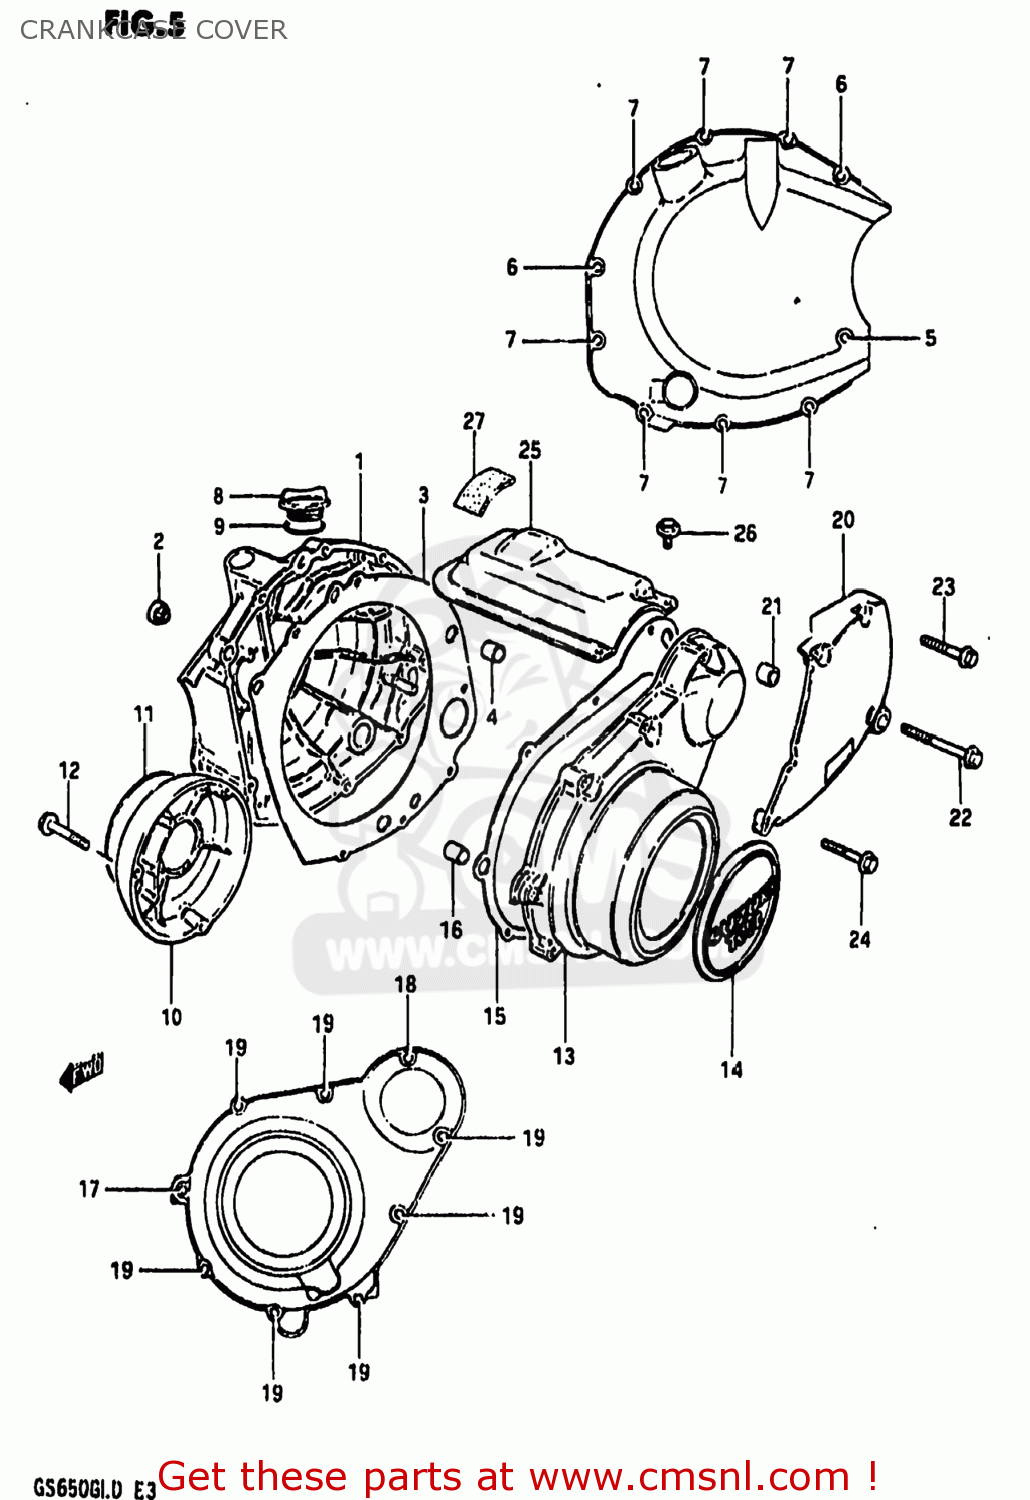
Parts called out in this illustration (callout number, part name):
1	COVER,CLUTCH
2	LENS,OIL LEVEL CHECK
3	GASKET,CLUTCH COVER (MCA)
4	PIN
5	BOLT (6X65)
6	BOLT (6X40)
7	BOLT (6X30)
8	PLUG
9	O-RING
10	COVER,CONTACT BREAKER
11	EMBLEM
12	BOLT (5X30)
13	COVER,MAGNETO
14	EMBLEM,MAGNETO COVER
15	GASKET,MAGNETO COVER (MCA)
16	PIN
17	BOLT
18	BOLT (6X35)
19	BOLT (6X30)
20	COVER,SECONDARY DRIVE
21	PIN
22	BOLT (6X40)
23	BOLT (6X30)
24	BOLT
25	COVER,STARTER MOTOR
26	BOLT
27	DAMPER,STARTER MOTOR CLUTCH
